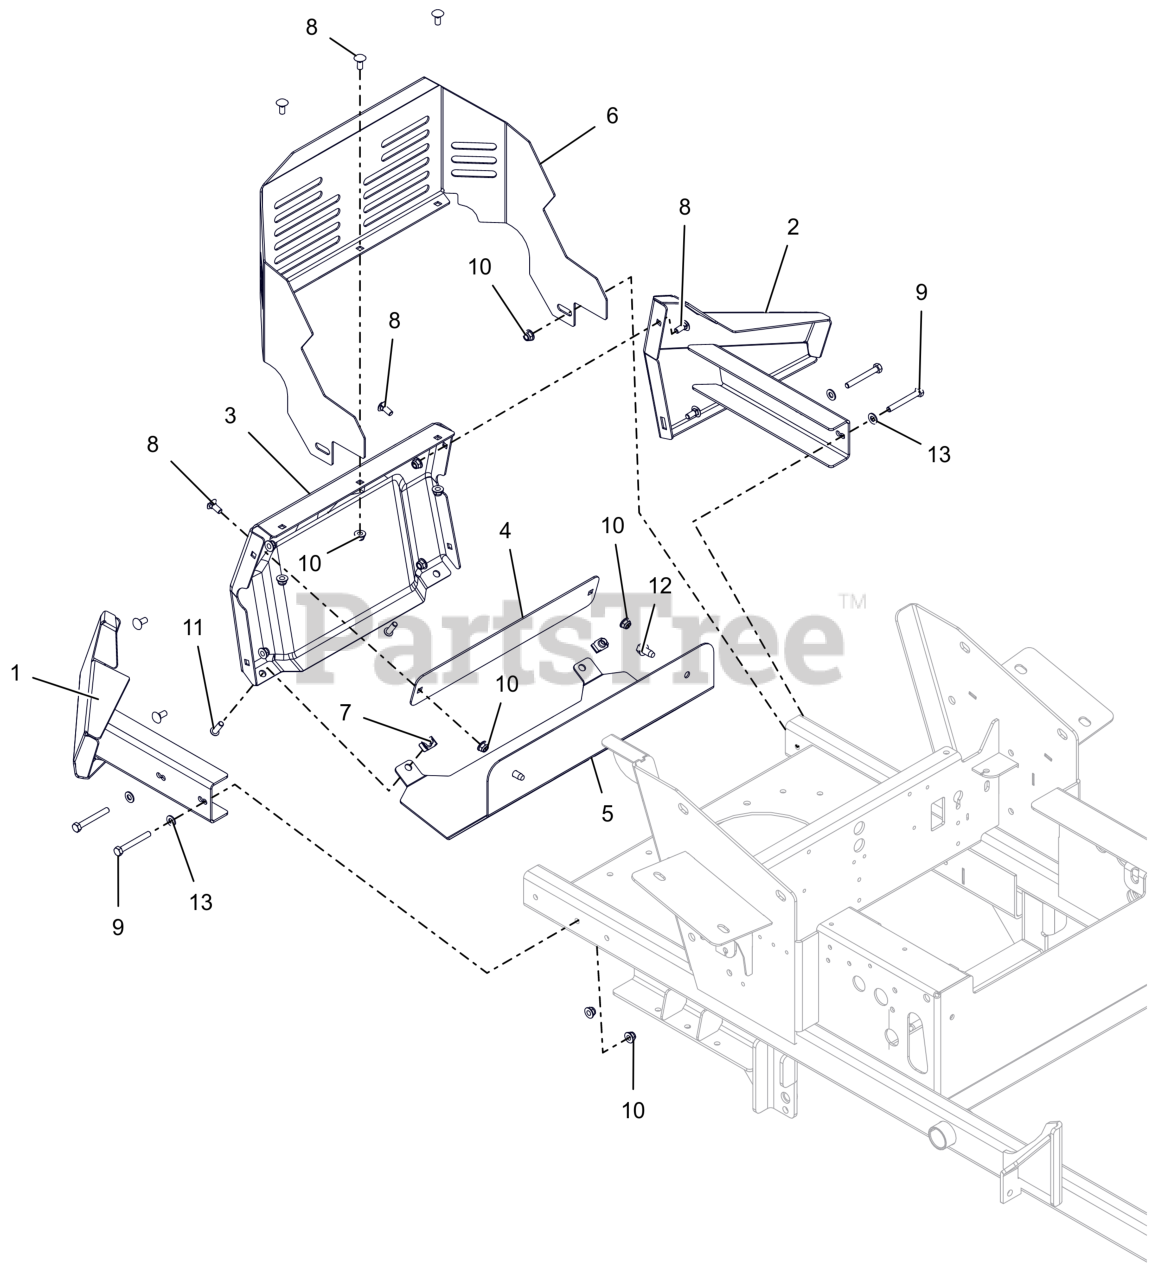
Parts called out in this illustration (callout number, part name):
1	RH RR BMPR WING W/SAFETY DECAL
2	LH RR BMPR WING W/SAFETY DECAL
3	PT200/400 REAR BUMPER - BLACK
4	BACKER PLATE - RED
5	PT100 MUFFLER GUARD -BLACK
6	GUARD, PT100 ENGINE
7	NUT-CLIP RETAINER 5/16-18X.56
8	BLT,RHSN .31-18X.75 G5 ZCC
9	BLT, HEX 0.3125-18X2.5 GR5 ZCC
10	NUT,NYL-FLG .31-18 GF ZCC
11	BLT,SHCS-BTN .31-18X1.00 ZCC
12	SCR,TAP .375-16X.75 HWH TR ZCC
13	WSHR,FLT .344X.688X.065 ZCC
